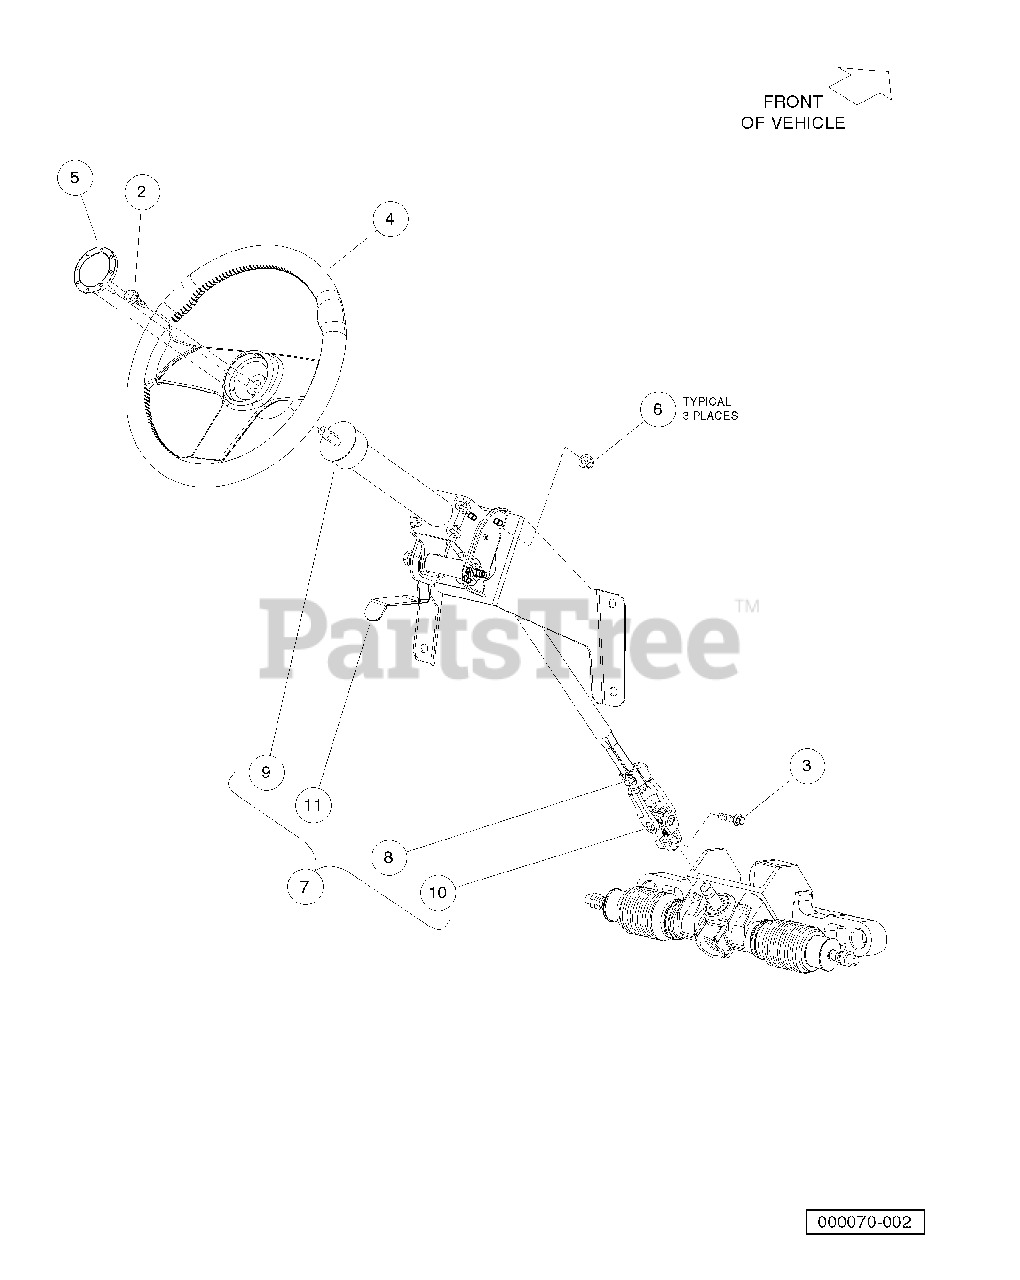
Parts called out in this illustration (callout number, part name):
1	Instl, Steering System
2	Bolt, M10 X 20 Hex Washer Hd
3	Bolt, Flange Head, M8 X 30.0
4	Steering Wheel, Viper, Hex Hub
5	Cap, Steering Wheel, Viper
6	Lock Nut, Flg M8 X 1.25 Nylon
7	Steering Column
8	Bolt, Flange Head, M8 X 30.0
9	Shroud, Steering Column
10	Bolt, M4 X .7 X 60
11	Handle, Steering, Tilt
